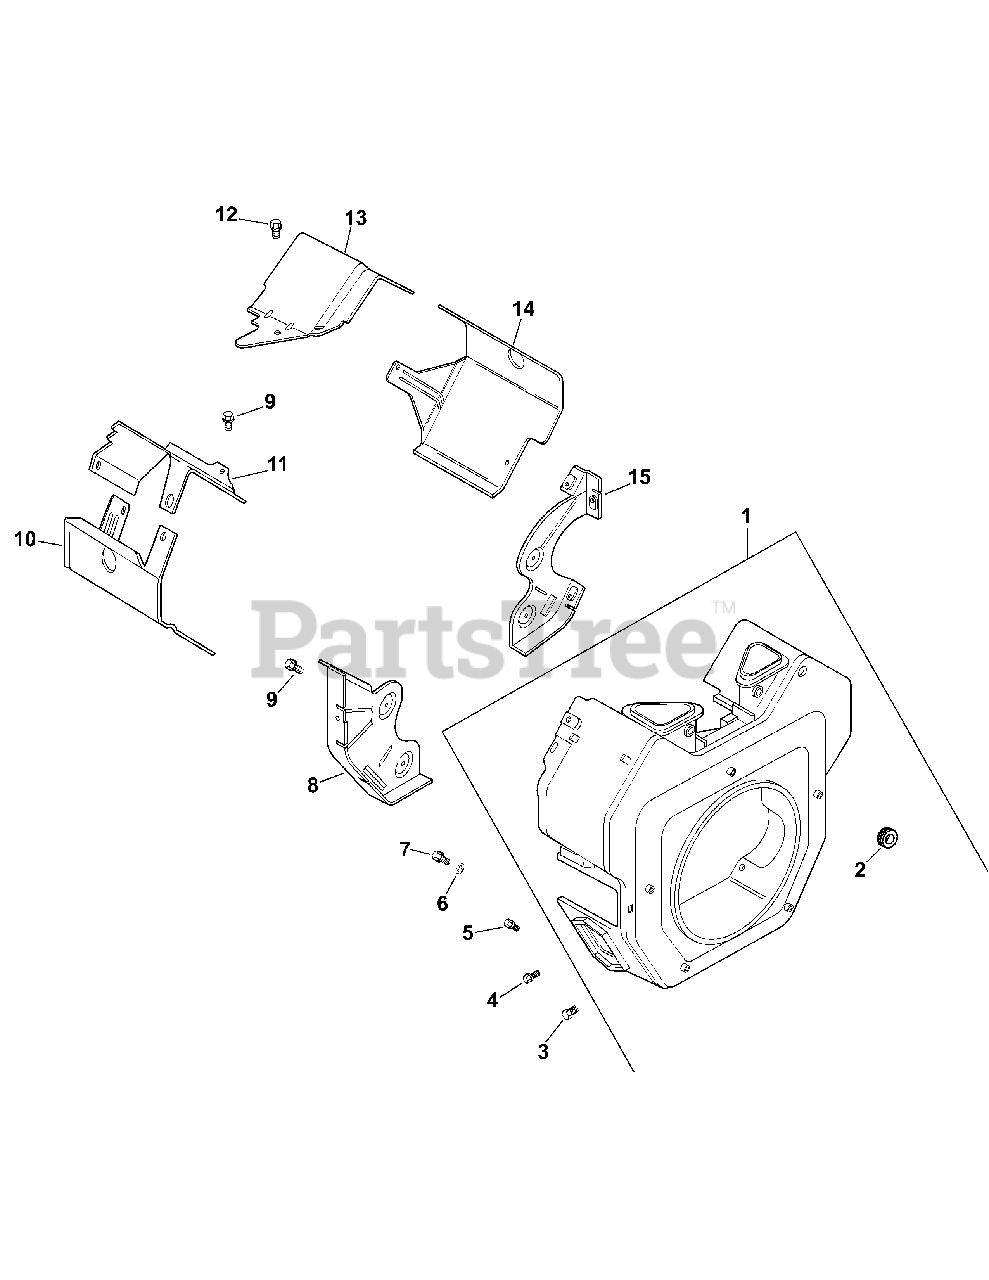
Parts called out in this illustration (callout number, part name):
1	Housing, blower
3	Screw, hex. flange M5x0.8x16
4	Screw, hex. flange M5x0.8x16
5	Screw, hex. flange M5x0.8x20
6	Washer, plain
7	Screw, hex. flange M5x0.8x25
8	Plate, backing - #2 side
9	Screw, hex. flange M6x1.0x16
10	Baffle, cylinder barrel - #2 side
11	Baffle, valley - #2 side
12	Screw, hex. flange M5x0.8x10
13	Baffle, valley - #1 side
14	Baffle, cylinder barrel - #1 side
15	Plate, backing - #1 side
